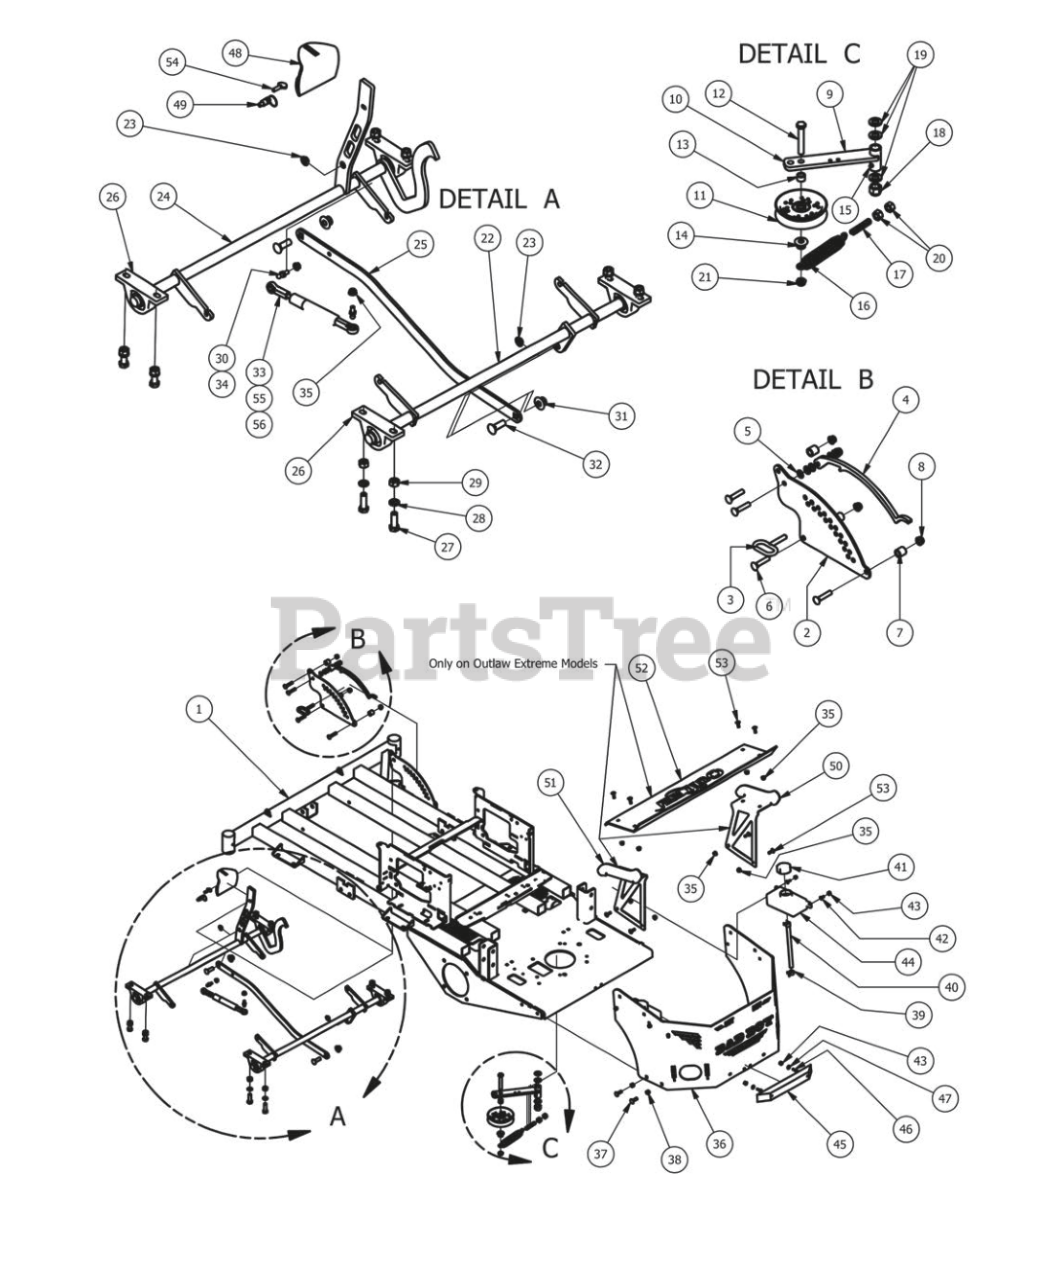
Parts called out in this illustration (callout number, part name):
1	Outlaw Frame
2	Outlaw Height Indicator Plate (Outer)
3	Deck height lever pin
4	Outlaw Deck Lever Lock
5	.390 x .750 x .062 Nylon Washer
6	3/8 x 1 3/4 Carriage Bolt
7	3/4 OD x 1/2 ID x 3\4 Length
8	3/8" Nylock Flange Nut
9	Deck Idler Assembly Componets 10,11,12,13,14,15
10	Deck Idler Bracket
11	4-3/4 Idler Pulley
12	1/2-13 x GR 5 Hex Bolt Zinc
13	1/2 x 1/2 Spacer
14	1/2-13 Nylon Flange Nut-Orange
15	1/4" Drive in Grease Fitting
16	Pump Idler Spring
17	All Thread-pump Idler Tensioner
18	5/8 Std NC Nylock Nut
19	.635] Plastic Washer
20	1/2" Hex Nut
21	1/2" Nylcock Nut (1/2 Jam)
22	Outlaw Actuator Bar (Rear)
23	Bushing- SF-1620-4
24	Outlaw Front Actuator Bar Assembly
25	Outlaw Deck Linkage Rod
26	Pillow block Bearing
27	1/2" x 1 1/2" Hex Bolt
28	1/2" Lock Washer
29	1/2" Hex Nut
30	10mm Damper Ball Stud-Steering Only on 54" & 61" Decks
31	1/2-13 Nylon Flange Nut-Orange
32	1/2 x 1-1/2 Carriage Bolt
33	200 lb Gas Spring- 54" Deck outlaw
34	13mm Damper Ball Stud for 72" Deck only
35	5/16-18 Hex Flange Nuts
36	Outlaw Rear Plate
37	3/8" x 1 1/4" Carriage Bolt
38	3/8 Nylock Nut
39	5/8 Hose Clamp
40	5/8 Braided Hose
41	Hydraulic Tank Cap
42	1/4" x 3/4" Carriage Bolt
43	1/4-20 Nylon Insert flange Nut
44	Expansion Tank Outlaw
45	14" Rubber Bumper
46	1/4-20 x 1-1/4 GR 5 Hex Bolt
47	1/4" Flat Washer
48	Outlaw Deck Lift Pedal
50	Spoiler Side Support Right
51	Spoiler Side Support Left
52	Outlaw Spoiler Plate
53	5/16" x 1" Carriage Bolt
54	5/16-18 x1 Thumb Screw Zinc
55	300 lb Gas Spring - 72" Deck Outlaw
56	250 lb Gas Spring -61" Deck outlaw
